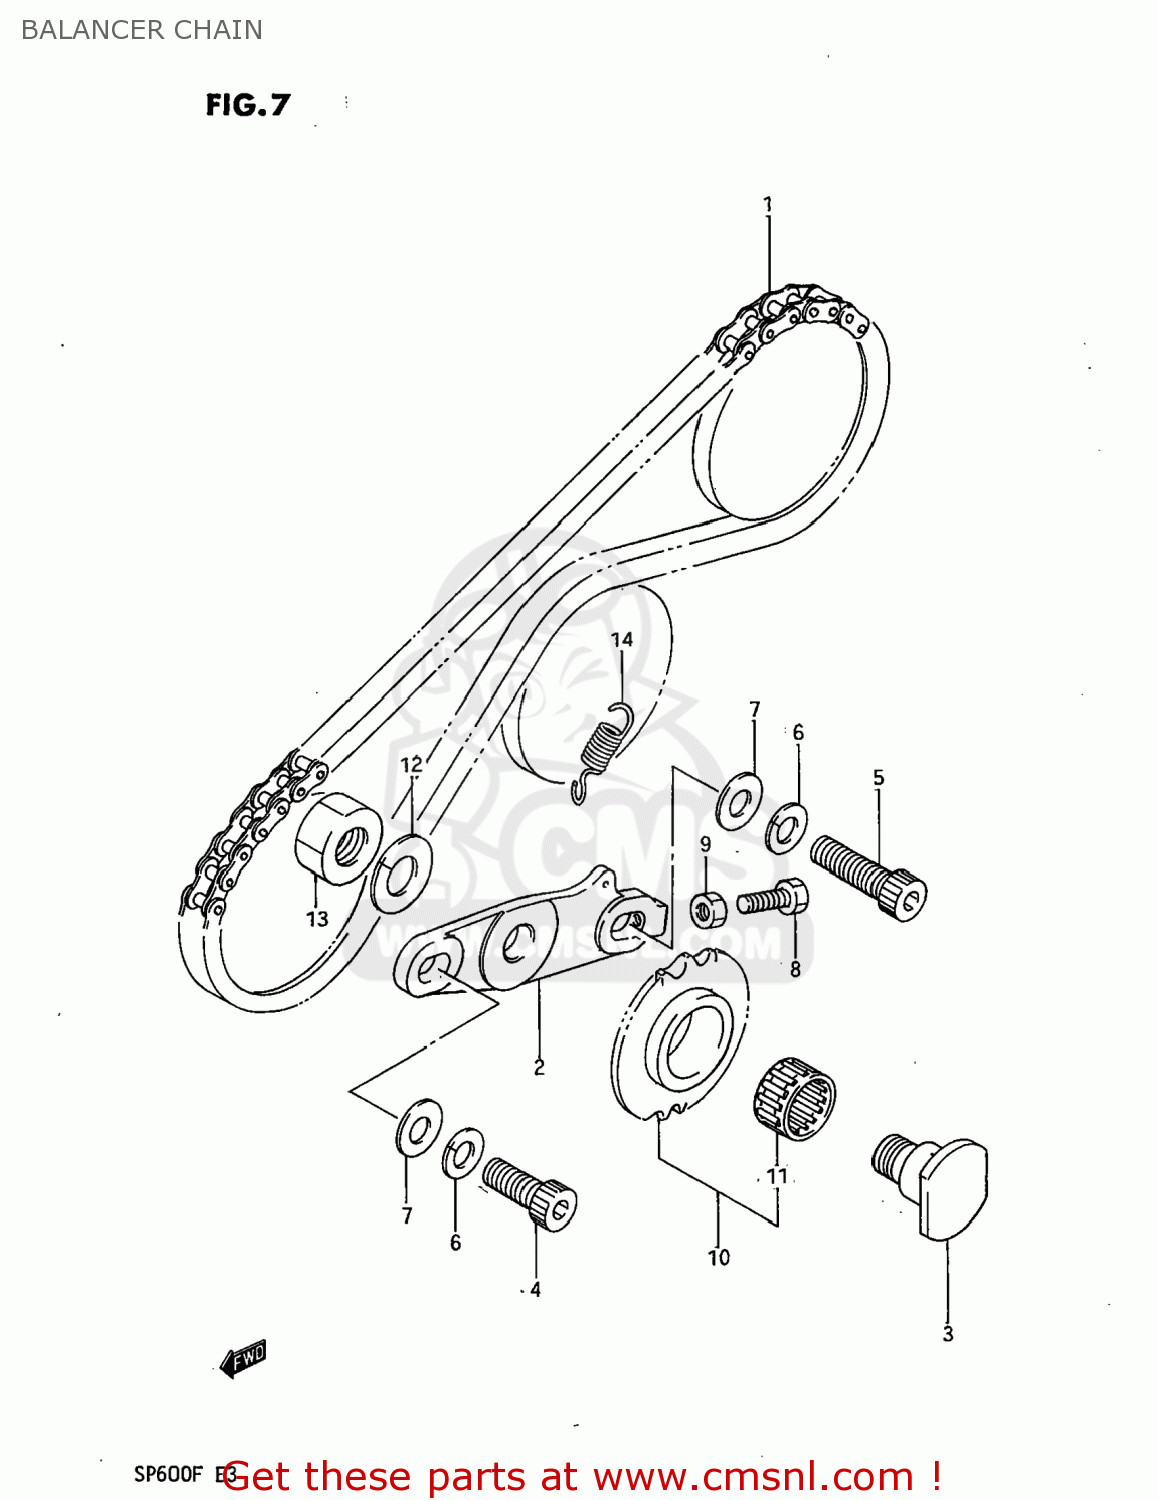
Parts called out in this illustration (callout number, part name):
1	CHAIN,BALANCER
2	BRACKET,BALANCER CHAIN
3	SHAFT,BALANCER CHAIN TENSIONER
4	BOLT(8X22)
5	BOLT, REAR (8X30)
6	LOCK WASHER
7	WASHER
8	BOLT 5X20
9	NUT
10	SPROCKET,BALANCER CHAIN
11	BEARING(17X23X12)
12	WASHER,LOCK 12
13	NUT
14	SPRING
